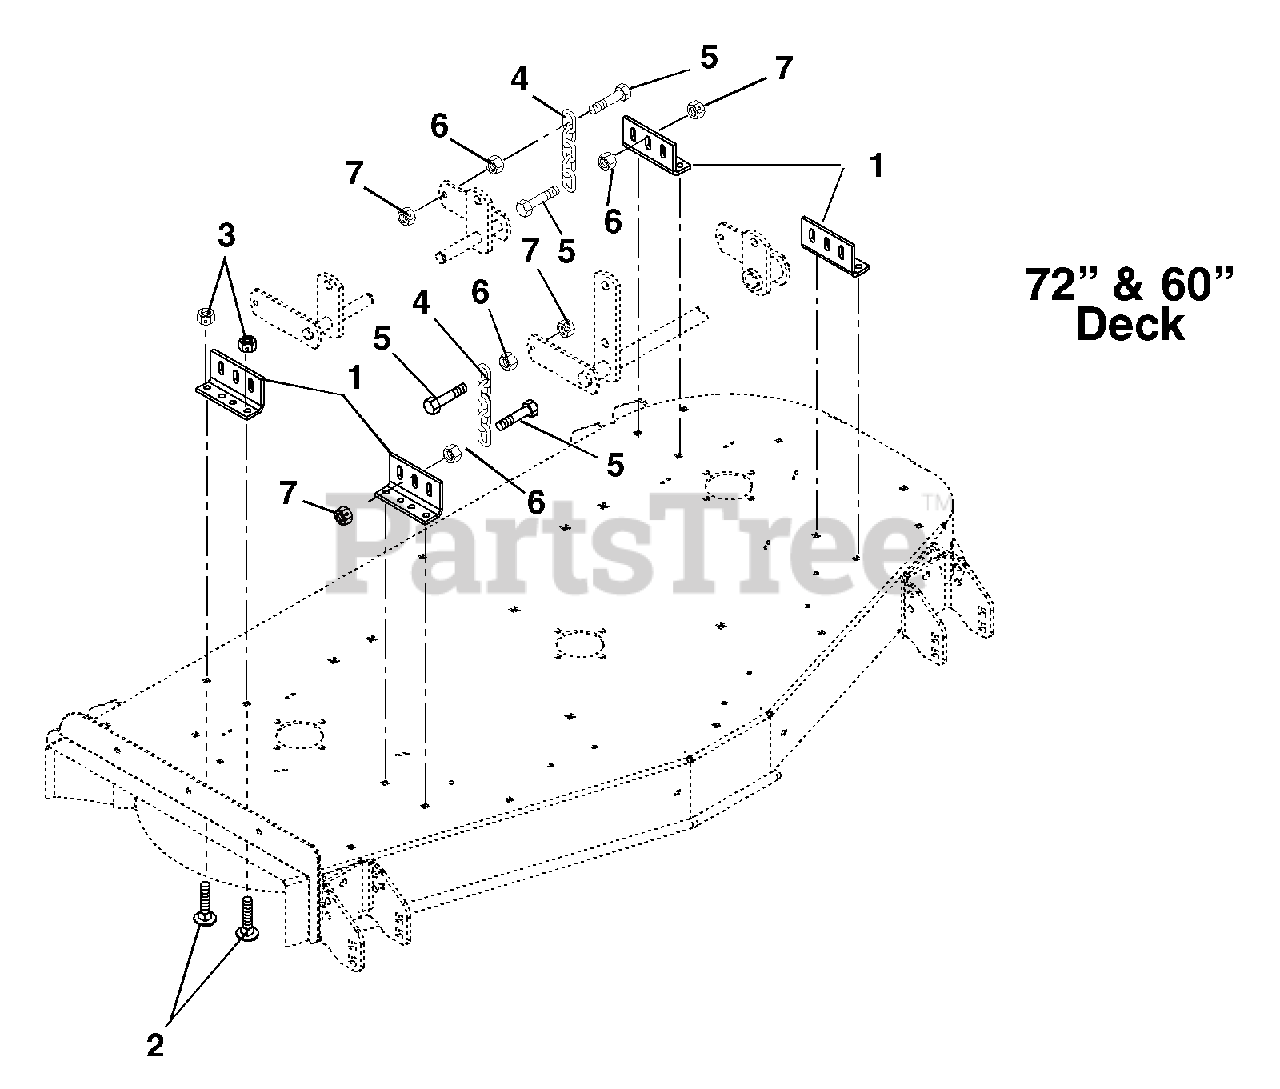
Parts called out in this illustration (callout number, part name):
1	Bracket, Mower Mounting
2	Bolt-Round Head Square Neck .38-16 x 1.00 Grade 2
3	Nut-Locking-Top-Flange .38-16
4	Chain, Link
5	Bolt-Hex .50-13 x 2.00 Grade 5
6	Nut, Spin Lock Flange .5-13
7	Nut-Locking-Top-Flange .50-13
